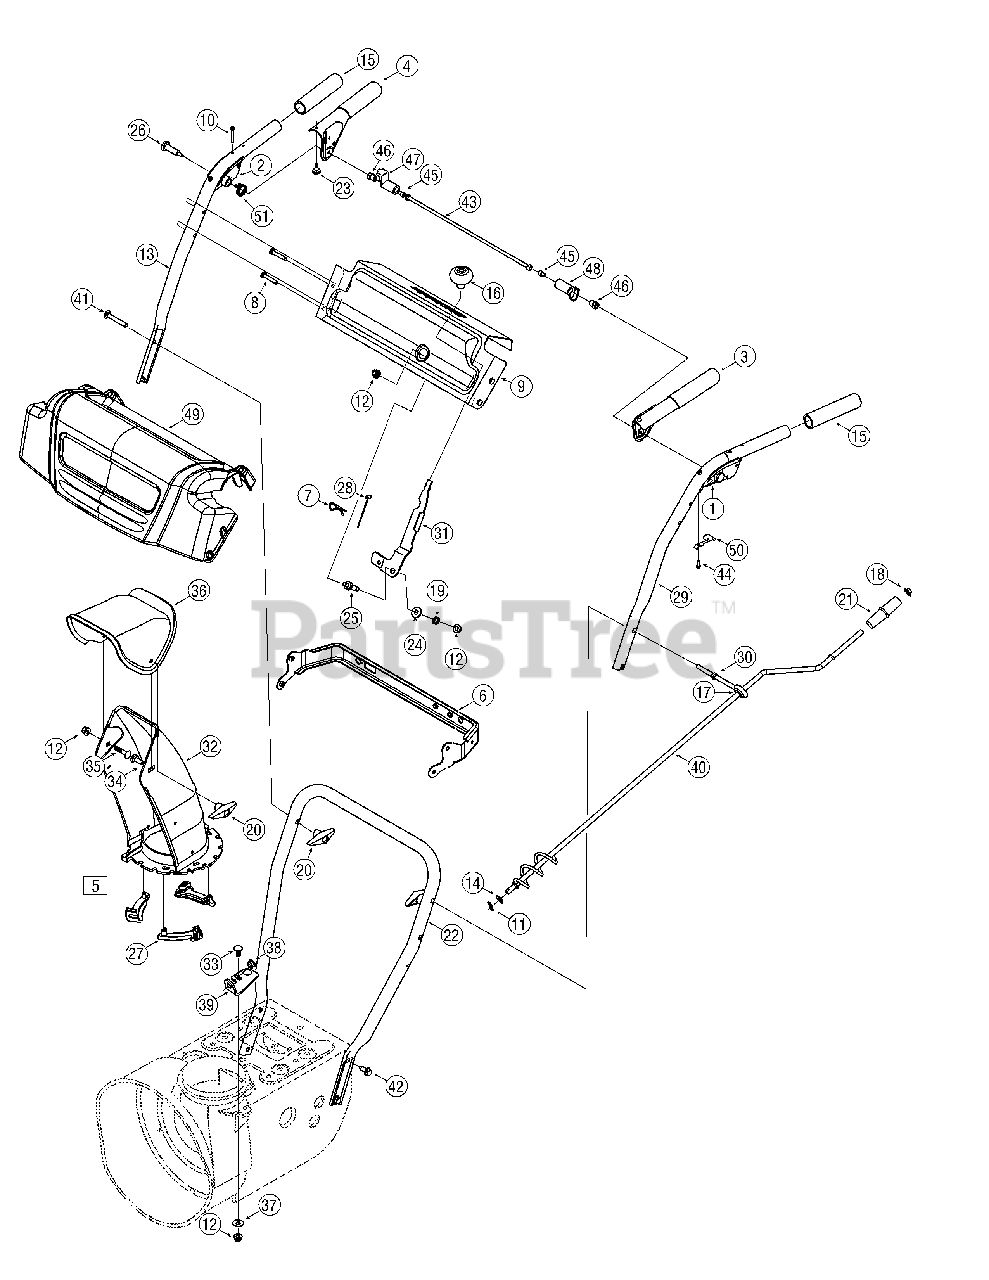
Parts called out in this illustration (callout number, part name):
1	Handle Assembly, Clutch Lock, LH
2	Handle Assembly, Clutch Lock, RH
3	Handle Ass’y, Engage, LH
4	Handle Ass’y, Engage, RH
5	Chute, Lower (Incl. Ref. # 27, Qty. 3)
6	Bracket, Panel
7	Click Pin
8	Screw, 1/4-20 x 1.625
9	Panel, Handle, (no cutout)
10	Screw, Machine, #10-24, 1.375
11	Pin, Cotter, .072 x 1.13
12	Nut, Flange Lock, 5/16-18, Nylon
13	Handle, Upper, RH
14	Washer, Flat, .375 x .738 x .063
15	Grip, 1.0 ID x 5.0
16	Knob, Shift, Black
17	Grommet, .44 ID x .94 OD x .50
18	Cap, Push, 3/8 Rod
19	Spring, .39 x .60 x .88
20	Knob, 5/16-18, Black
21	Crank Knob, 1.0 Dia. x 3.2, Black
22	Handle, Lower
23	Bumper, Rubber, .62 OD x .22
24	Washer, Flat, .385 x .870 x .092
25	Bolt, Shoulder, 5/16-18 x 0.905
26	Screw, Shoulder, .43 x 1.3, 1/4-20
27	Chute, Flange Keeper
28	Cable, Speed Selector
29	Handle, Upper, LH
30	Eye Bolt, Chute Crank
31	Shift Lever
32	Chute, Lower, 5.0 Dia.
33	Bolt, Carriage, 5/16-18, 1.0
34	Bolt, Carriage, 5/16-18, 1.0
35	Bolt, Carriage, 5/16-18, .750
36	Chute, Upper, w/ Label
37	Washer, .349 x .879 x .063
38	Bushing, Plastic, .380
39	Bracket, Chute Crank
40	Crank Assembly, Chute
41	Screw, Carriage, 5/16-18, 2.25
42	Screw, 5/16-18, 2.25, Gr5
43	Rod, Pivot
44	Screw, #8-16 x .50
45	Screw, 1/4-20 x .50
46	Nut, Hex, 1/4-20
47	Plate, Lock
48	Cam, Clutch Lock
49	Handle Panel Cover
50	Spring, Clutch Lock
51	Spring, Torsion, .8156 ID x .3038
